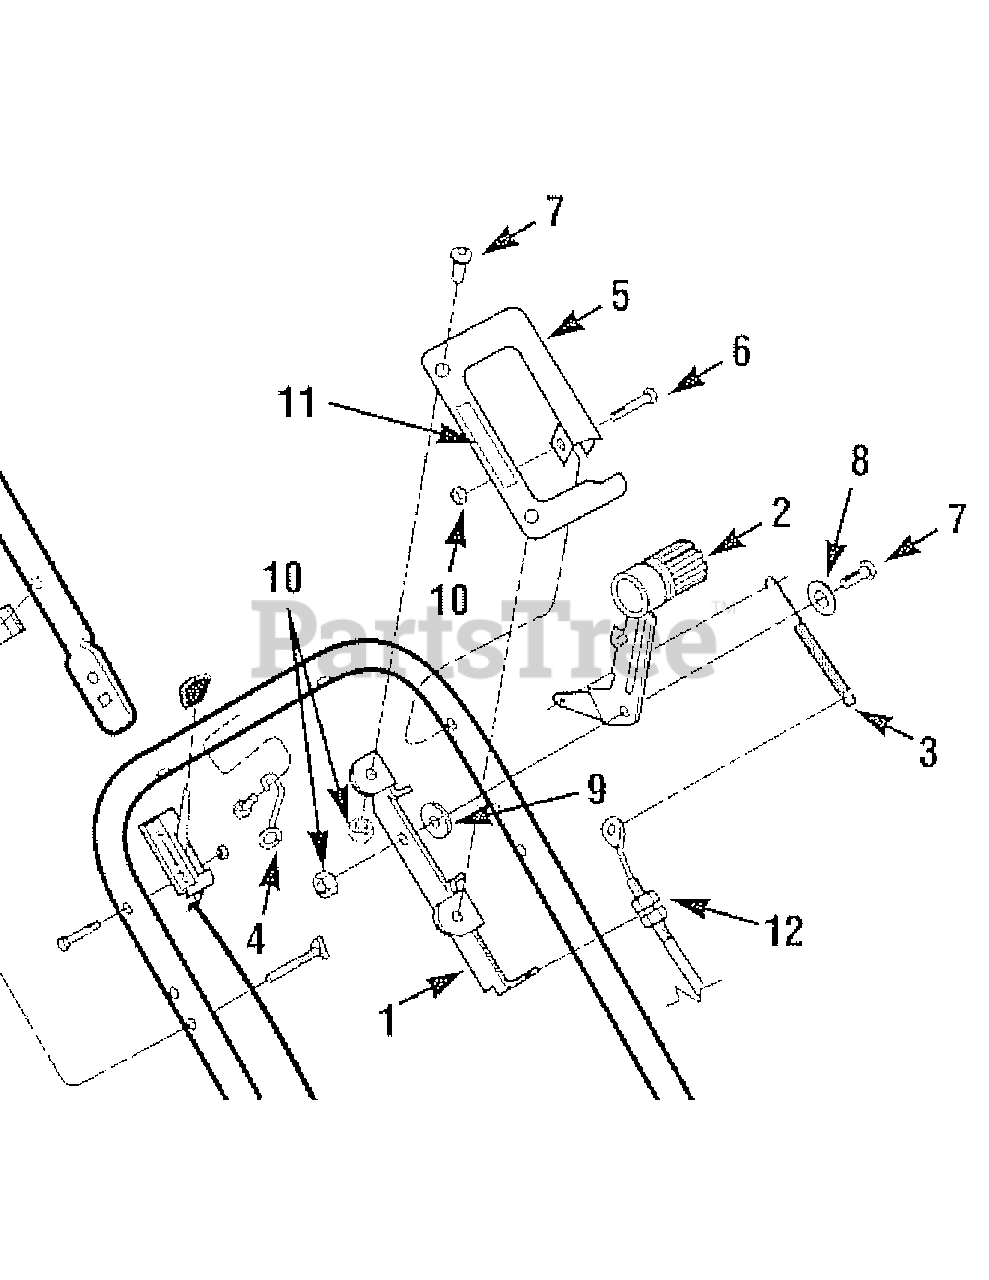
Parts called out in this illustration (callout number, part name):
1	SUPT-CONTROL DRIVE {34021}
2	ARM-CONTROL {34021}
3	SPRING-EXTENSION {34021}
4	GUIDE-ROPE {34021}
5	MOUNT-DRIVE CONTROL {34021}
6	SCR 1/4-20X1.5 PL CSHH {34021}
7	SCR-RH 1/4-20X.75 {34021}
8	WASHER-BELLEVILLE {34021}
9	BUSHING, NYLON {34021}
10	NUT-HT LK 1/4-20 {34021}
11	DECAL-WHEEL DRIVE {34021}
12	CABLE-DRIVE CONTROL {34021}
